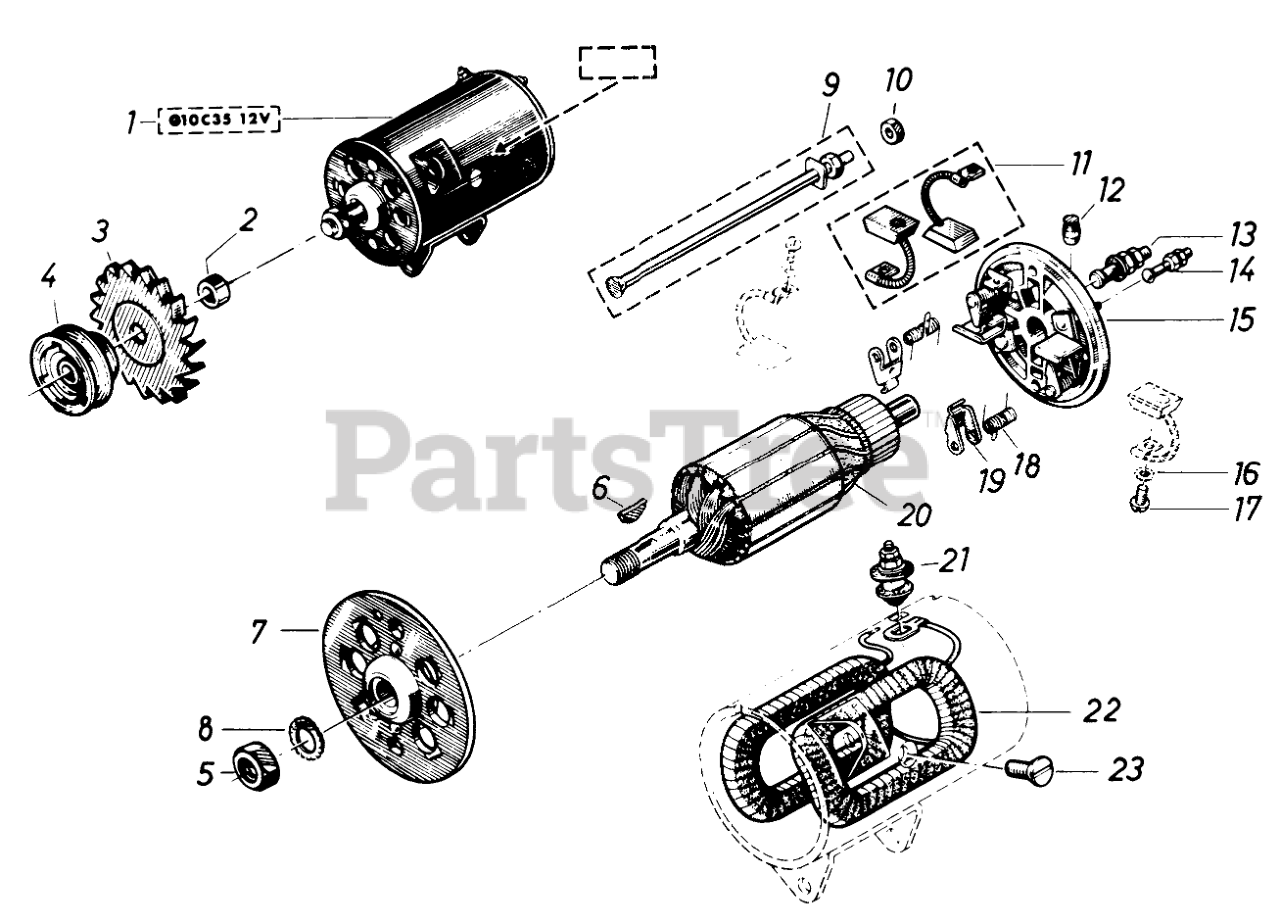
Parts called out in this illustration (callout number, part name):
1	Generator
2	Spacer
4	Pulley
7	Bearing
8	Lock Washer
9	Screw
11	Brush Set
12	Lubricating Felt
13	Clamp
14	Earthing Clamp
15	Commutator End Plate Assembly
16	Lock Washer
17	Screw
18	Spring
19	Brush Holder
20	Armature
21	Clamp
22	Field Winding
23	Screw
